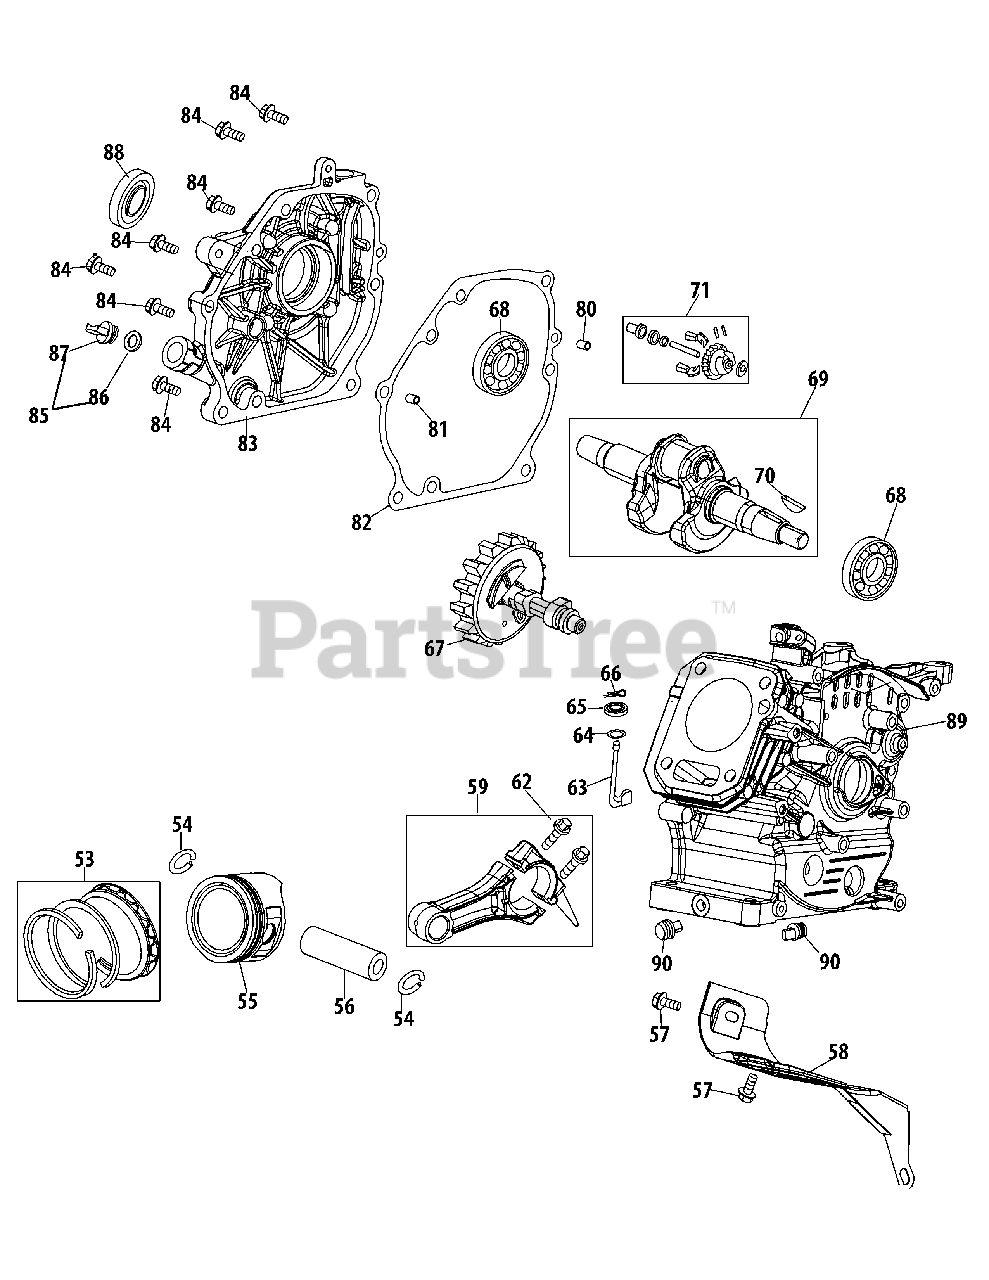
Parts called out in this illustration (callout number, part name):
53	Piston Pin Set
54	Piston Pin Snap Ring
55	Piston
56	Piston Pin
57	Bolt M6×12
58	Air Shield
59	Connecting Rod Assembly
62	Connecting Rod Bolt
63	Governor Arm
64	Washer 5.2×1.9
65	Governor Seal
66	Cotter Pin
67	Camshaft Assembly
68	Radial Ball Bearing, 6205
69	Crankshaft Assembly
70	Woodruff Key
71	Governor Gear Assembly
80	Dowel Pin 7×14
81	Dowel Pin 9×14
82	Crankcase Cover Gasket
83	Crankcase Cover
84	Bolt M8×32
85	Dipstick Assembly
86	O-Ring 15.8×2.5
87	Oil Plug
88	Oil Seal, 25×41.25×6
89	Crankcase
90	Oil Drain Plug
